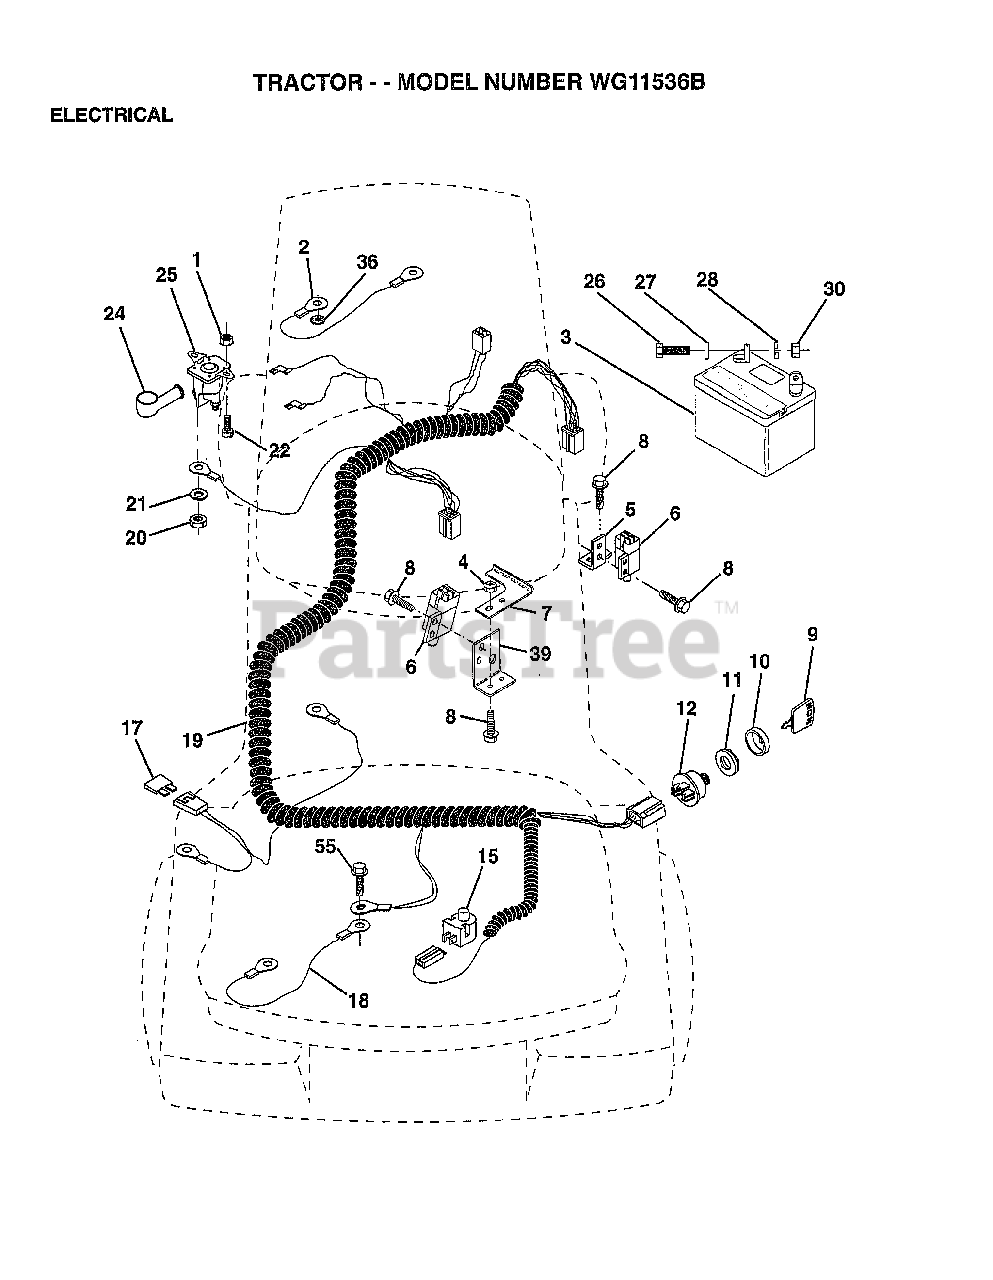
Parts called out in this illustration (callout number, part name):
1	NUT HXKEP 1/4X20
4	LOCKNUT
5	BRACKET LT
6	SWITCH INTERLOCKT
7	KEEPER.ACTUAT.LR.
8	SCREW
9	KEY STEEL DELTA
10	COVER KEY SWITCH
12	SWITCH.IGNITION
15	SWITCH SEAT
17	FUSE HYT
18	CABLE ASSY
19	HARNESS.IGN.FEND.
20	NUT
22	BOLT HXHD FIN
27	WASHER
28	LOCKWASHER
36	LOCKWASHER
39	BRACKET SWT CLUTC
